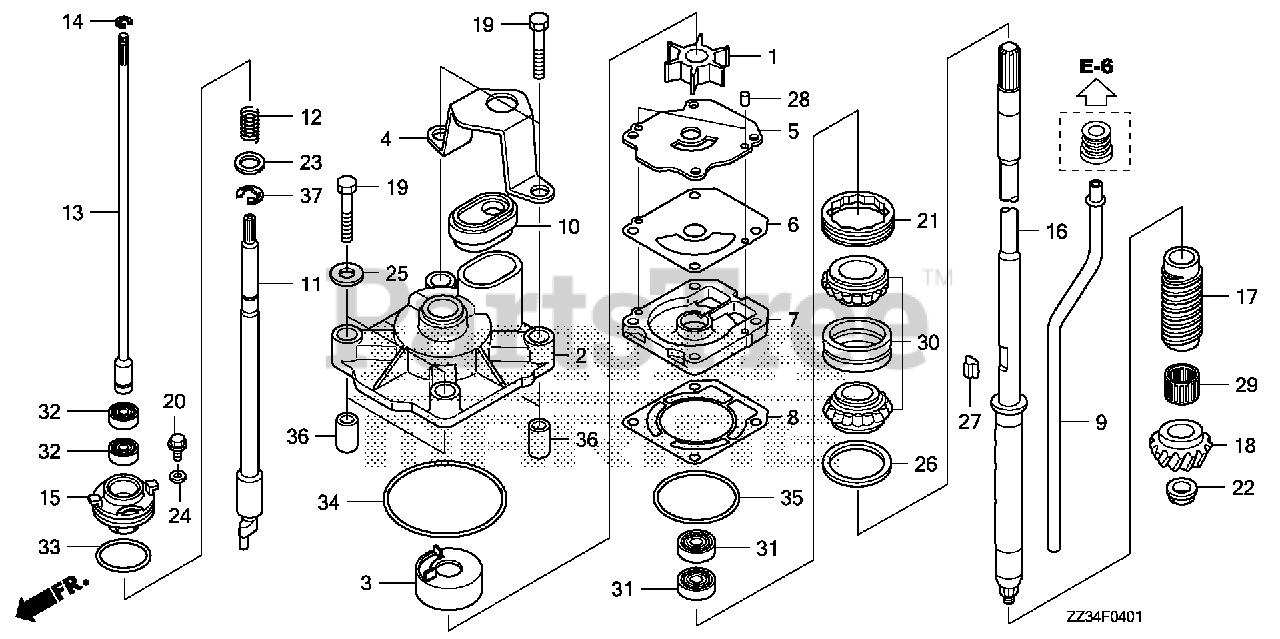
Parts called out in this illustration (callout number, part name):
1	IMPELLER, PUMP
2	HOUSING, IMPELLER
3	LINER, PUMP
4	HOLDER, WATER TUBE SEAL
5	COVER, IMPELLER
6	GASKET B, IMPELLER (POWER THRUST)
7	HOUSING, WATER PUMP
8	GASKET, WATER PUMP
9	TUBE, WATER (L)(POWER THRUST)
10	RUBBER, WATER TUBE SEAL
11	ROD, SHIFT (L)
12	SPRING, SHIFT ROD
13	ROD A, SHIFT (L)
14	RING, STOPPER
15	HOLDER, SHIFT ROD
16	SHAFT, VERTICAL (L)(POWER THRUST)
17	SLINGER, OIL
18	GEAR, PINION (12T)
19	BOLT, HEX. (8X55)
20	BOLT, FLANGE (6X12)
21	NUT, LOCK (64MM)
22	NUT, HEX. (16MM)
23	WASHER, PLAIN (12MM)
24	WASHER, PLAIN (6MM)
25	WASHER (8MM)
26	SHIM A, GEAR (0.10)
26	SHIM B, GEAR (0.15)
26	SHIM C, GEAR (0.30)
26	SHIM D, GEAR (0.50)
27	KEY, WOODRUFF
28	PIN, DOWEL (6X10)
29	BEARING, NEEDLE (1-1/8X1-1/2X1-1/4)
30	BEARING, TAPER ROLLER (30X62X40)
31	SEAL, WATER (23X36X6)
32	SEAL, WATER (12X21X6)
34	O-RING, WATER PUMP
35	O-RING (58.5X3.5)
36	COLLAR, DISTANCE
37	E-RING (10MM)
